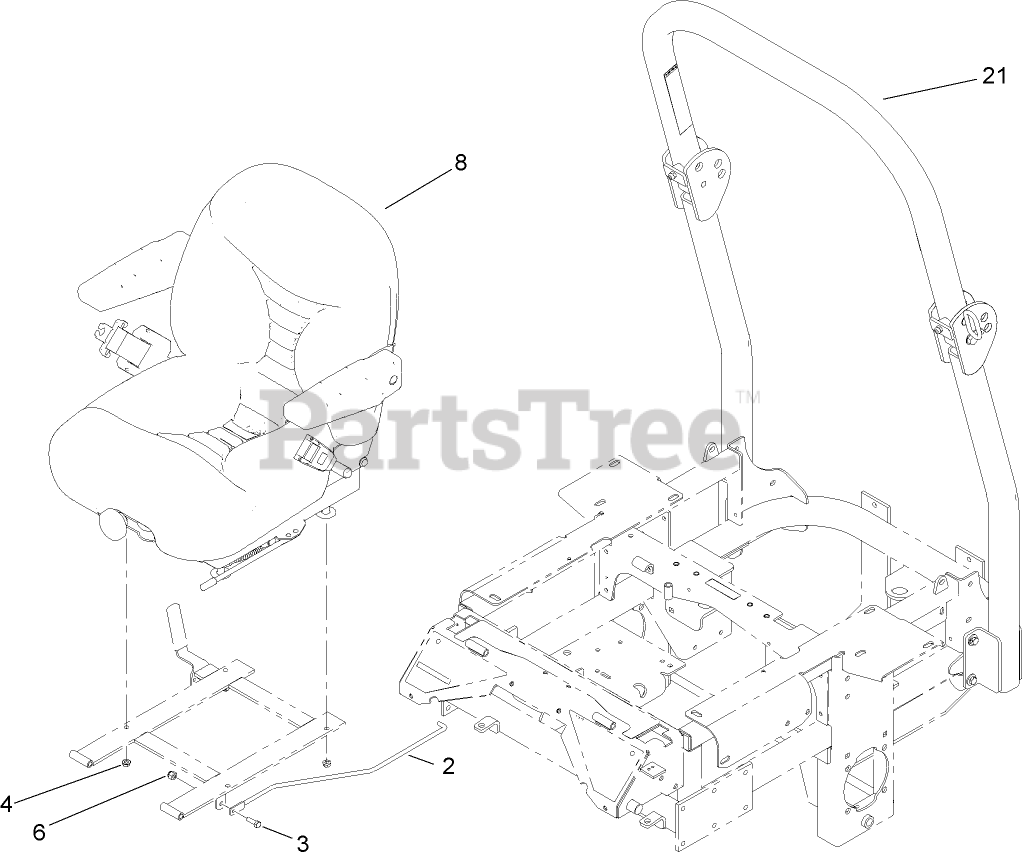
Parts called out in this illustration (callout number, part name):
2	ROD-PROP, SEAT
3	SCREW-HH
4	NUT-HF
6	NUT-LOCK, NI
8	DELUXE SEAT ASM
21	ROPS KIT
